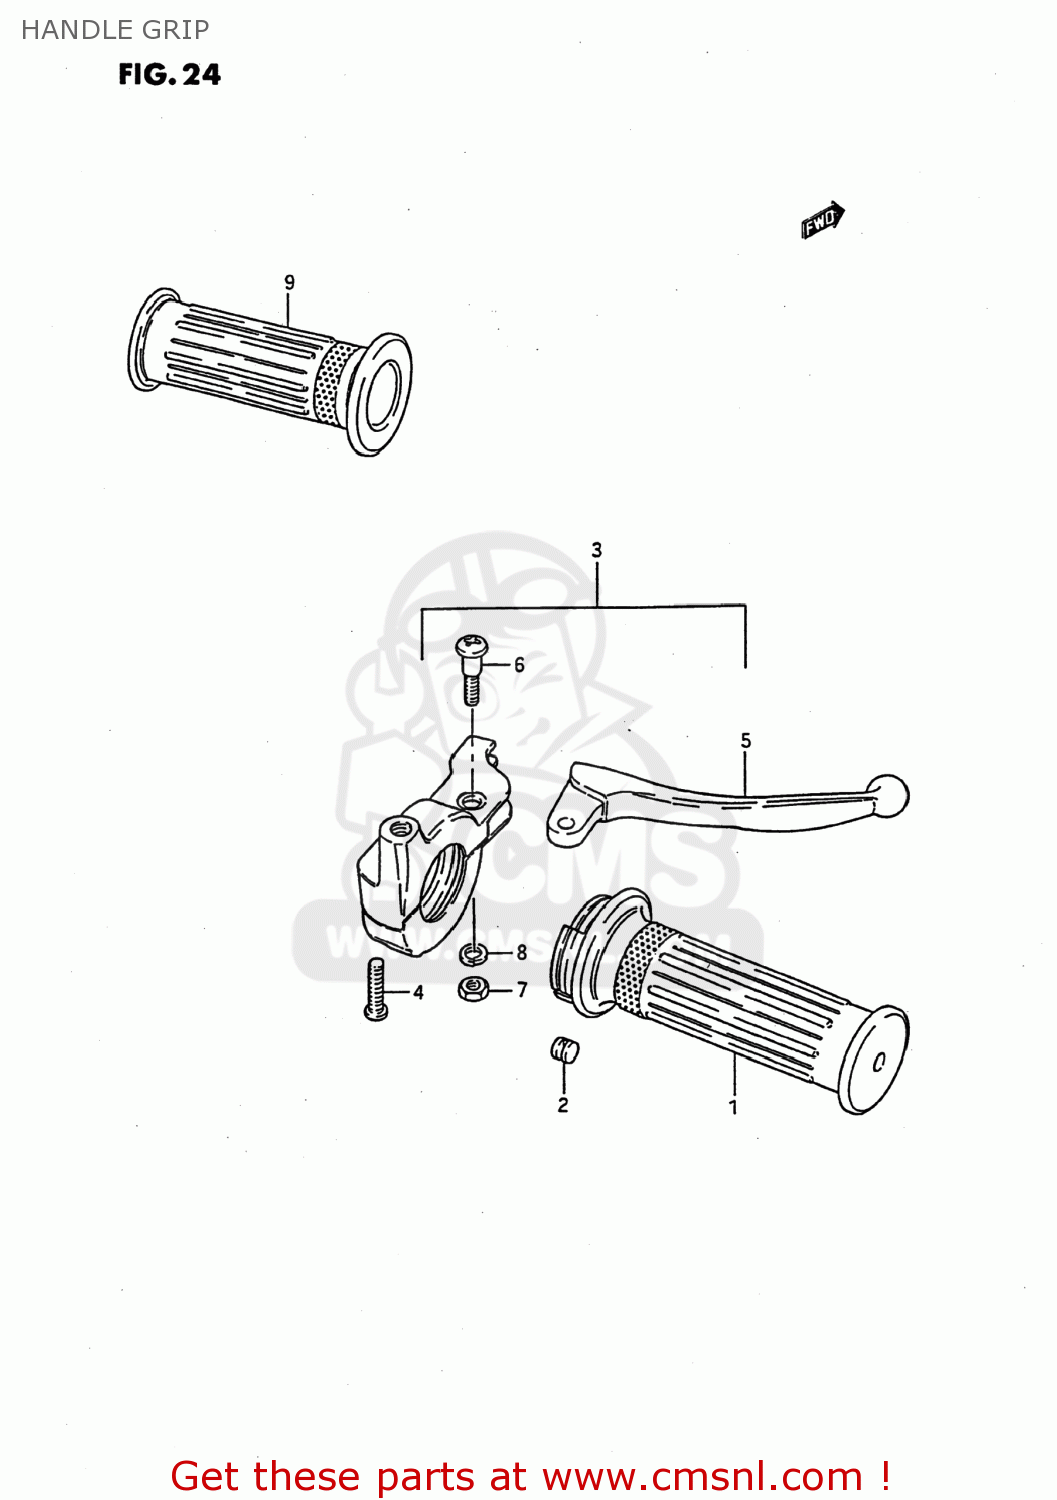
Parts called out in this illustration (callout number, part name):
1	GRIP,THROTTLE
2	PIECE,THROTTLE END
3	LEVER ASSY,BRAKE
4	SCREW(5X22)
5	LEVER,BRAKE
6	SCREW,BRAKE LEVER PIVOT
7	NUT
8	WASHER,LOCK
9	GRIP,L
